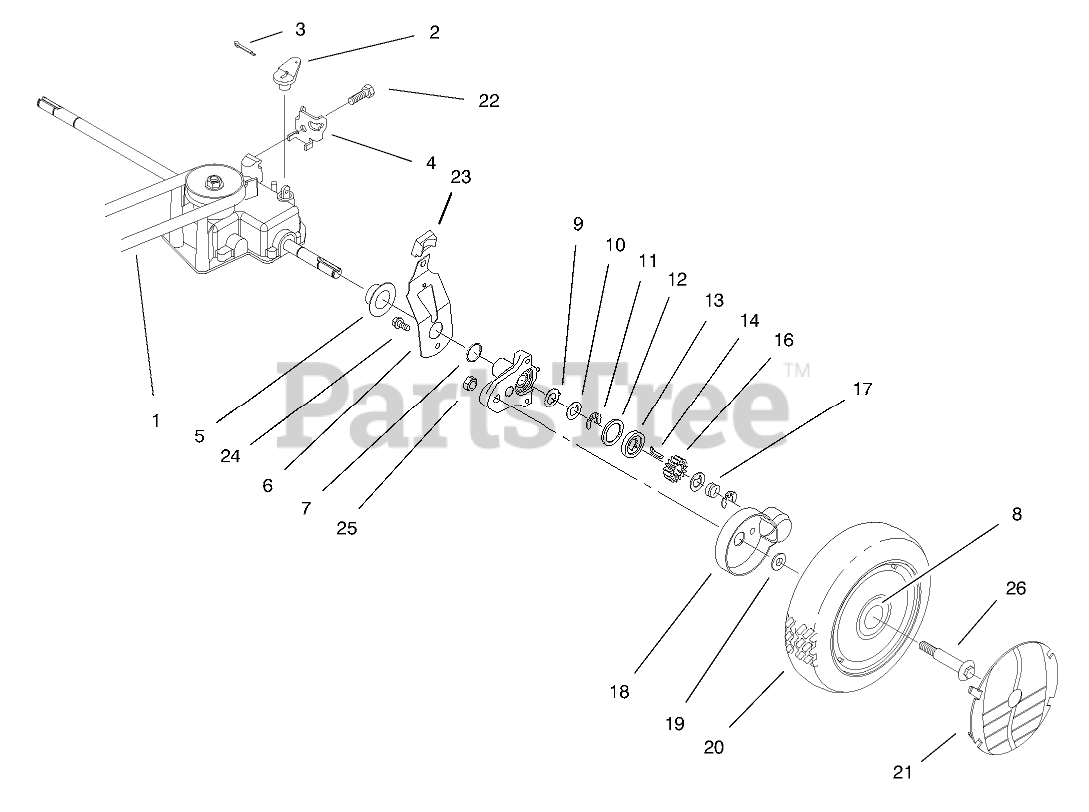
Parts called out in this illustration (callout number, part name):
1	V-BELT E
2	LEVER-SHIFT
3	PIN-COTTER
4	CLAMP-CABLE
5	CAP-END
6	SPRING ARM ASM
7	O-RING
8	BUSHING
9	WASHER-ARM, PIVOT
10	WASHER-THRUST, KEYED
11	RING-CLIP, LOCKING
12	RING-FRICTION
13	WASHER-CLUTCH
14	KEY-ROCKING, LH
16	GEAR-PINION
17	SPRING-COMPRESSION
18	COVER-WHEEL
19	SPACER-COVER, WHEEL
20	Wheel & Tire Assembly (Incl. Ref. #8)
21	WHEEL COVER
22	SCREW-HWHTF
23	KNOB-ARM
24	SCREW-HWH
25	NUT-LOCK
26	BOLT-WHEEL
